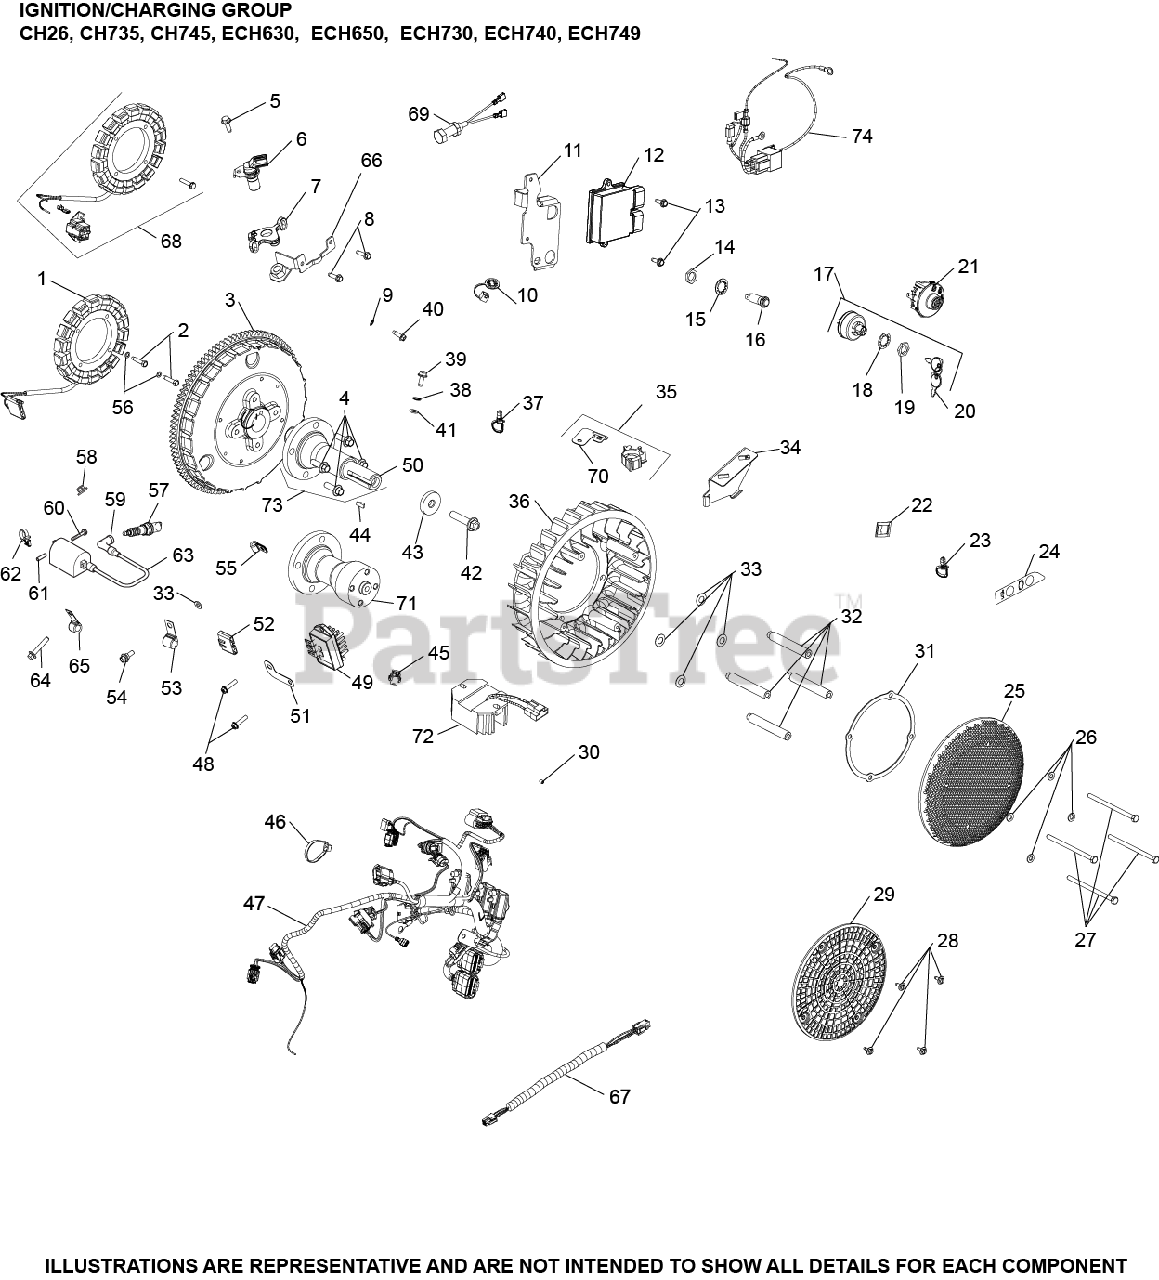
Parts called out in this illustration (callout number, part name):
1	KIT, 15 / 20 AMP STATOR
2	SCREW, THREAD FORMING
3	FLYWHEEL ASSEMBLY
5	SCREW, THREAD FORMING
6	SENSOR, SPEED
7	BRACKET, SENSOR MOUNT-(#2512616S)
8	SCREW, THREAD FORMING
9	WASHER, INT TOOTH LOCK #10
10	CAP, CONNECTOR
11	BRACKET, ECU
12	MODULE, ECU (ECH630) USE 24 584 183-S
16	LIGHT, INDICATOR
20	KEY, SET OF 2
21	KIT, KEY SWITCH (SNAP-IN)
23	TIE, WIRE
24	DECAL, WARNING LIGHT
25	KIT, GRASS SCREEN
28	SCREW, FLG SEMS M4X.7X25
30	SCREW, FLG M10X1.5X45 - (#25086361S)
35	KIT, MOUNTING CLIP
36	FAN USE 24 755 253-S
38	WASHER, INT TOOTH LOCK 1/4"
41	WASHER, FLAT 1/4" (O.D. 1/2")
43	WASHER, FLAT 13/32"
44	KEY, 3/16" X 5/8"
47	HARNESS, WIRING ASSEMBLY
48	SCREW, HEX FLANGE HI-LO
49	REGULATOR, RECTIFIER USE 25 403 32-S
51	BRACKET, GROUND STRAP USE 24 518 12-S
52	CONNECTOR
54	BOLT, SHOULDER
56	WASHER, FLAT 3/16"
57	PLUG, SPARK (STD)
63	COIL, IGNITION-EFI - USE 25 519 02-S
64	SCREW, FLG M6X1.0X34
